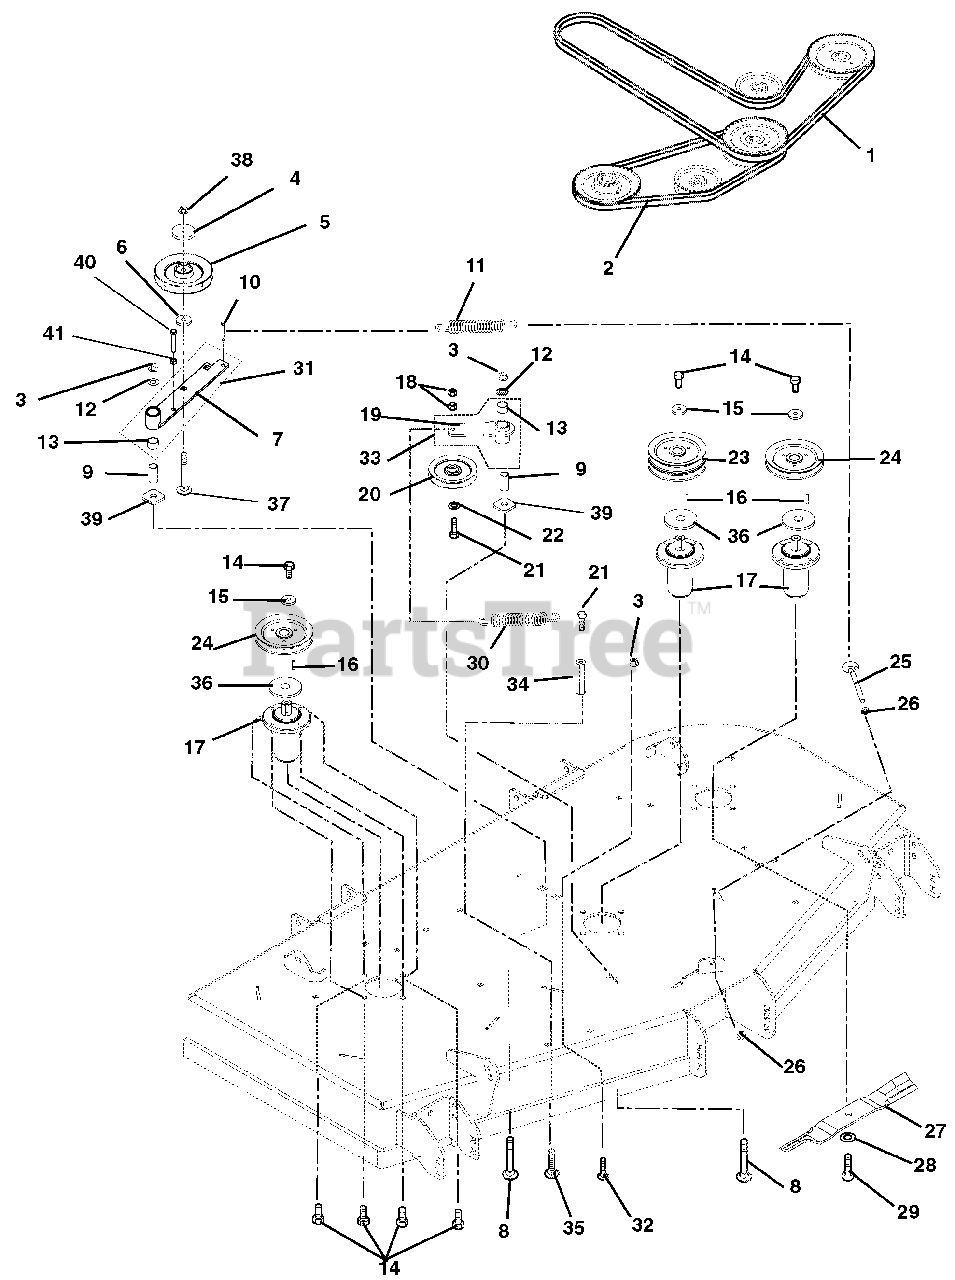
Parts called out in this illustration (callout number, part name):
1	HEX BELT, BB-WRAPPED
2	V-BELT, B-COGGED
3	@NUT-LK-NYL-FLG .50-13 YWZC
4	CAP, IDLER BEARING SEALING
5	PLY-V 6.0 X .500 ID SNGL BRG.
6	BSHG, SPCR .502X.997X.50 PM
7	WMT, IDLER ARM
8	@BLT-RHDSSQNK .50-13X3.50 G5YZ
9	BSHG, SPCR .502X.997X2.03 PM
10	BLT,SHLDR EP .38-16X.30 HEX YZ
11	SPRING, EXTENSION
12	WSHR-FL-STL .531X1.250X.10 YWZ
13	BSHG, 1.00 X 1.125 X 1.937
14	BLT-HEX .38-16X1.0 GR8 YZ EP30
15	WSHR,FLT STL.406X1.50X.245YWZC
16	KEY, SQ .25X.25X1.00 RC 40-50
17	ASSEMBLY, SPINDLE
18	@NUT-LK-CTR .38-16 YWZC
19	WMT, IDLER ARM
20	ASM, V-IDLER 5.00 O.D.
21	@BLT-HEX .38-16X2.25 GR5 YWZC
22	@WSHR-FL-STL.406X.812X.065 YWZ
23	SHEAVE, DOUBLE 1"ID X 6.00"OD
23	SHEAVE, DOUBLE 1"ID X 6.75"OD
23	SHEAVE, DOUBLE 1"ID X 8.25"OD
24	SHEAVE, SINGLE 1"ID X 6.00" OD
24	SHEAVE, SINGLE 1"ID X 6.75"OD
24	SHEAVE, SINGLE 1"ID X 8.25"OD
25	BOLT, .38-16X4.50 .62 DIA EYE
26	NUT-HEX-JAM .375-16 YWZC
27	BLADE, MULCH 18.00"
27	BLADE, MULCHING (20.50")
27	BLADE,MOWER-72"MULCH(24.5"LG)
28	WSHR-BLVL .669X1.535X.138
29	BLT-HEX .62-18X1.75 GR8 YWZC
30	SPRING, EXTENSION
31	ASM, IDLER PIVOT ARM (PTO)
32	BLT-RDHDSHSQNKFT.50-13X1.50 G5
33	ASM, IDLER ARM (DECK)
34	NUT COUPLING .375-16X1.75
35	@BLT-RDHDSHSQNK.38-16X1.0 G5YZ
36	RETAINER, GREASE
37	@BLT-RDHDSQNK .50-13X3.00 G5YZ
38	@NUT-LK-NYL-FLG .50-13 YWZC
39	WSHR-FLT .640X1.75X.250
40	@BLT-HEX .38-16X2.75 GR5 YWZC
41	@NUT-HEX .38-16 YWZC
